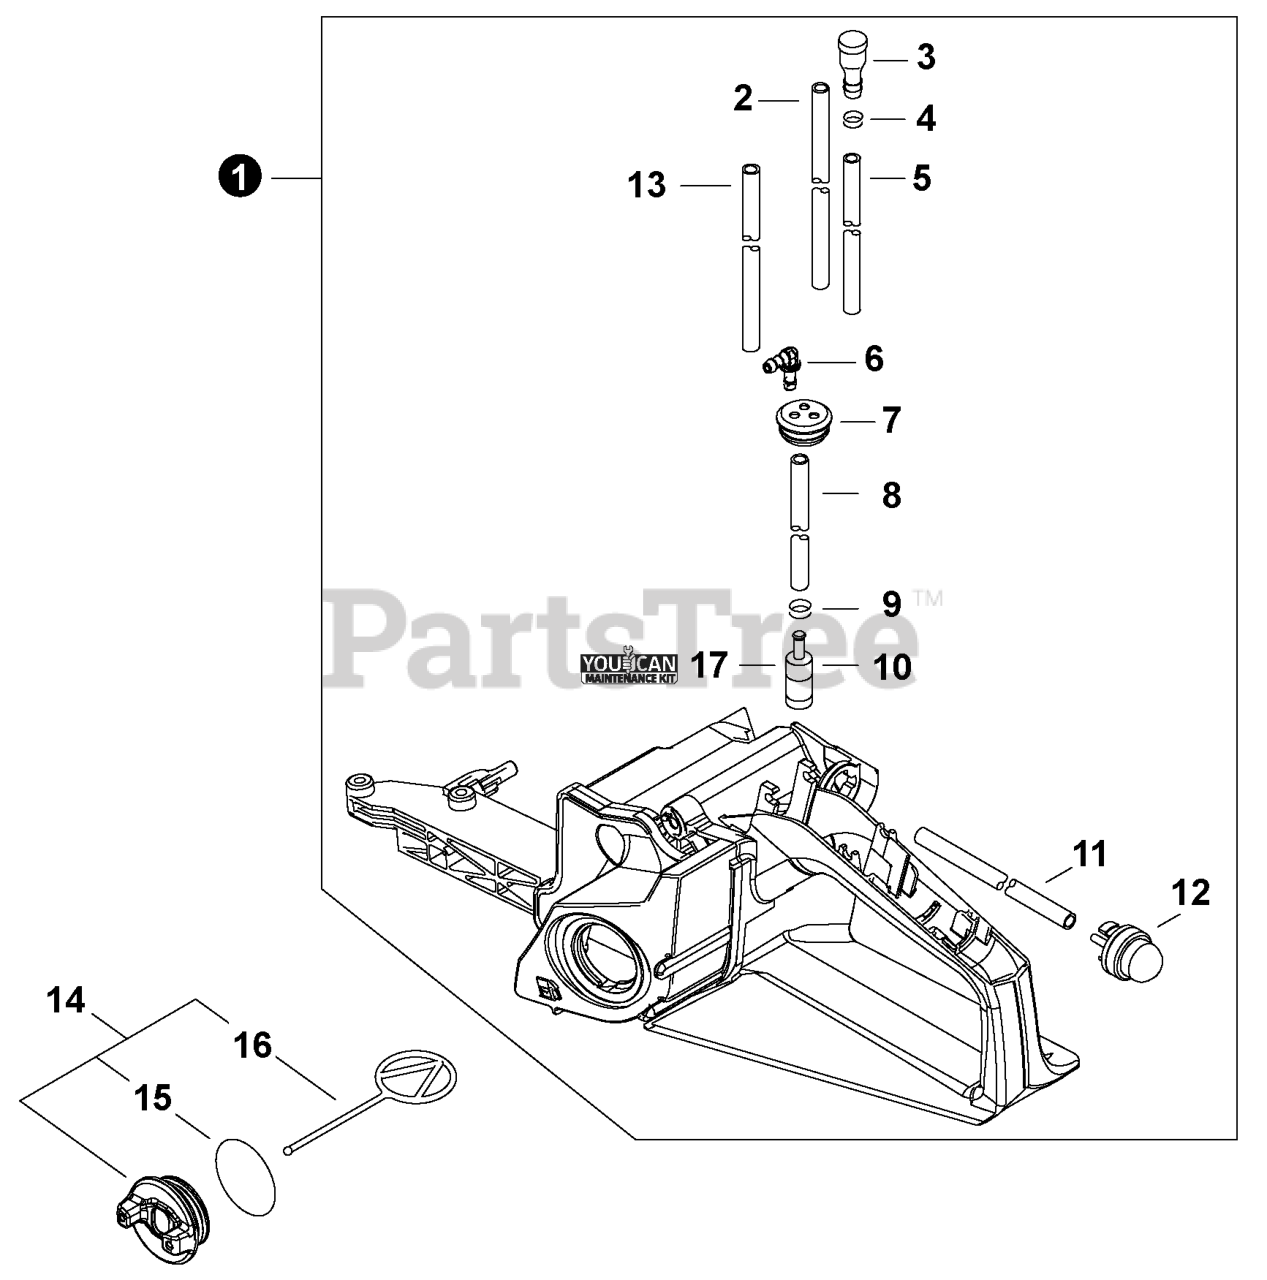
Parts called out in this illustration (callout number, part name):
1	HANDLE ASSY, REAR
2	PIPE, FUEL 2.4x5x75
3	VENT ASSY
4	CLIP 6.5 MM
5	PIPE 3x6x49
6	CONNECTOR, PIPE
7	GROMMET, FUEL
8	PIPE, FUEL 3x5x140 BLACK
9	CLIP 6
10	FILTER, FUEL
11	PIPE 2.4x5x165
12	BULB, PURGE
13	PIPE 3x5x160 EPA-KEP-002
14	CAP ASSY, FUEL
15	O-RING 29
16	CONNECTOR, CAP L= 60 MM
17	TUNE-UP KIT - YOUCAN™
